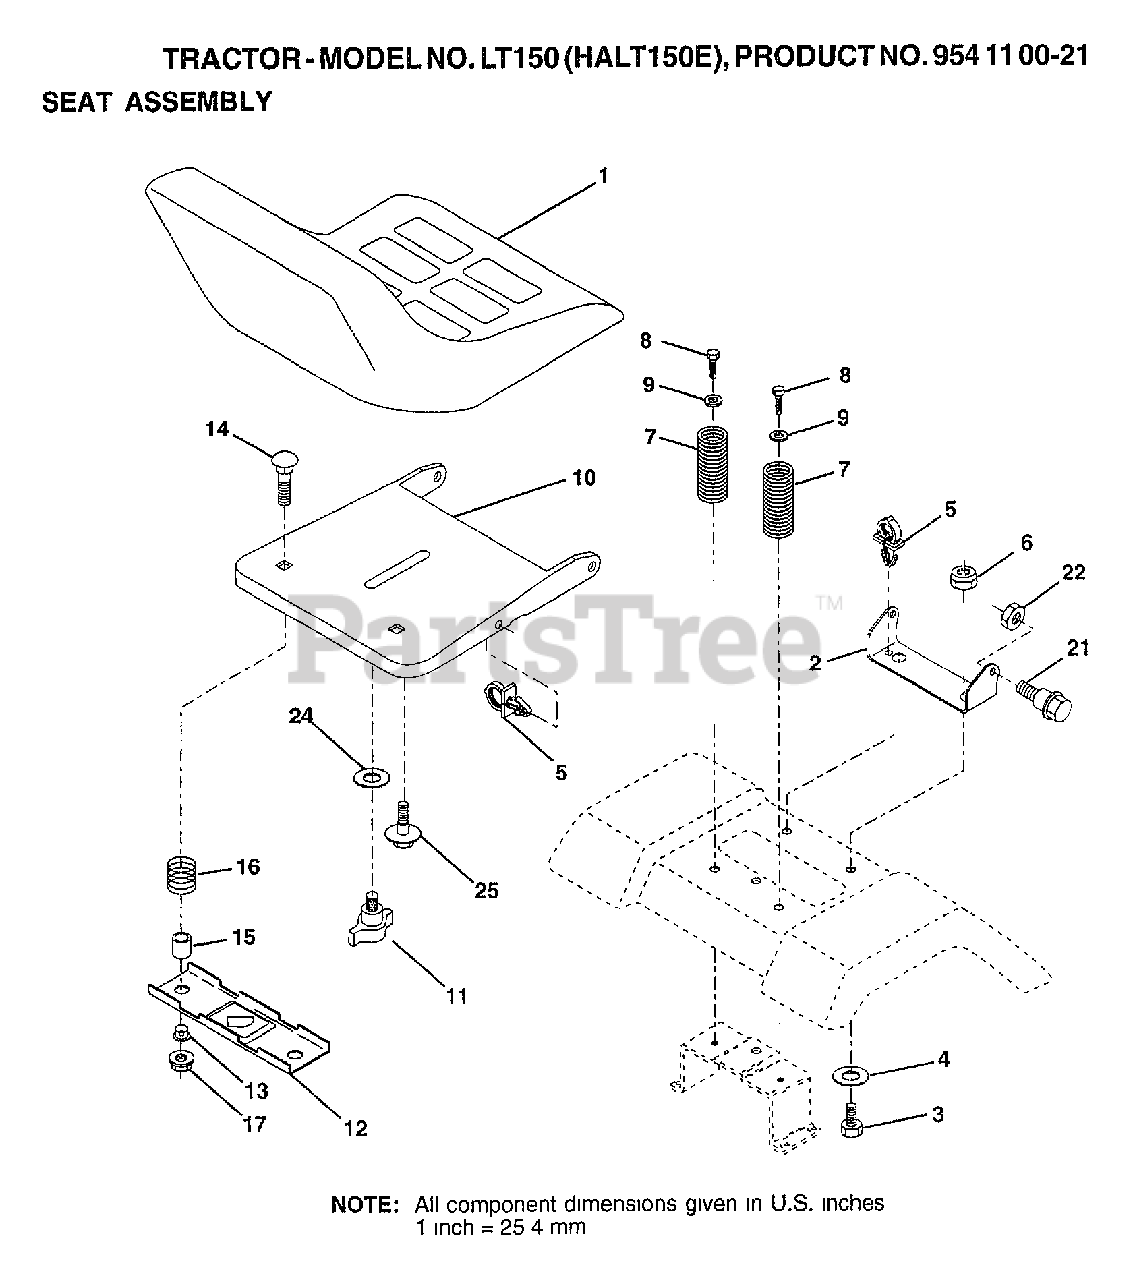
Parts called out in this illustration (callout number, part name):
1	SEAT.2400.GRY/BLK
3	BOLT FIN HEX 3/8-16 X 1
4	WASHER 13/32 X 1 X 10 GA
6	LOCKNUT
9	WASHER 13/32 X 1 X 14 GA
14	BOLT, CARRIAGE 1/4-20 X 1-1/2
21	BOLT
22	LOCKNUT
24	WASHER 17/32 X 1-3/16 X 12 GA
